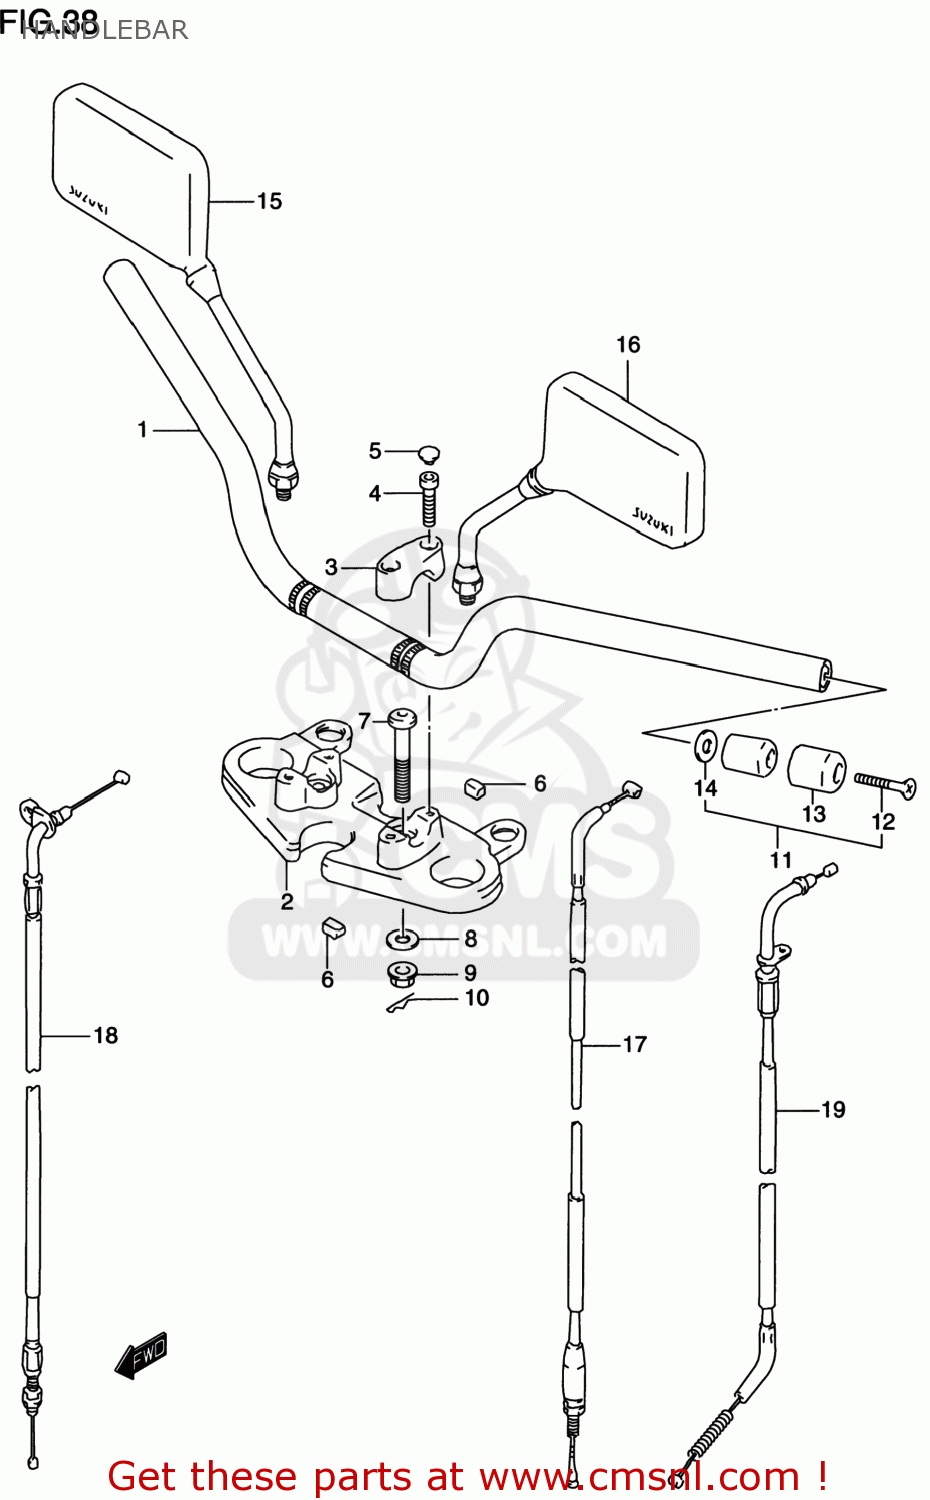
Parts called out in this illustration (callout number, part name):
1	HANDLEBAR
2	HOLDER,HANDLEBAR LWR
3	HOLDER,HANDLEBAR UPR
4	BOLT
5	CAP(OD:14.5)
6	CUSHION,HANDLE HOLDER
7	BOLT(10X66)
8	WASHER(10.5X30X3.2)
9	NUT
10	PIN 20X20
11	BALANCER SET,HANDLEBAR
12	SCREW
13	CAP,HANDLE BALANCER
14	SPACER,BALANCER
15	MIRROR ASSY,RR VIEW,R
16	MIRROR ASSY,RR VIEW,L
17	CABLE ASSY,CLUTCH
18	CABLE ASSY,THROTTLE
19	CABLE,STARTER
